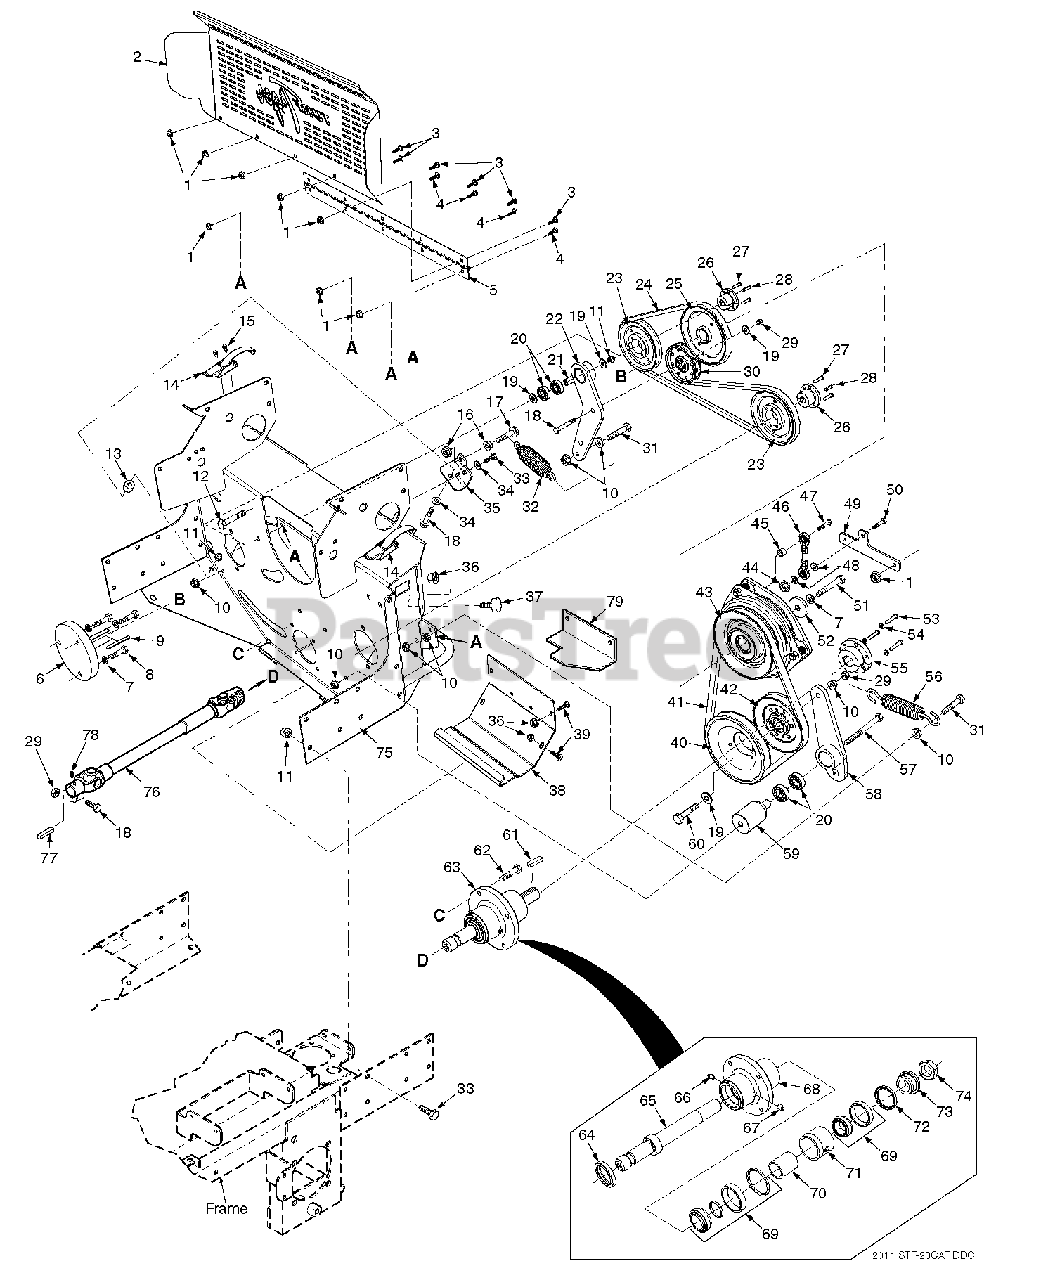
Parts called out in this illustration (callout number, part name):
1	Nut, Serrated Flange 1/4-20
2	Belt Guard, Rear
3	Bolt, Carriage 1/4-20 x 1/2"
4	Bolt, Carriage 1/4-20 x 3/4"
5	Hinge, Belt Guard
6	Stub Shaft
7	Lockwasher, 7/16" Spring
8	Bolt, Hex Head M10 x 1.5 x 35
9	Key, 1/4 x 1/4 x 3-1/4"
10	Nut, Serrated Flange 3/8-16
11	Nut, Elastic Stop 3/8-16
12	Bolt, Hex Head 3/8-16 x 1-3/4" Grd 8
13	Spacer
14	Latch, Hood
15	Screw, #10-32 x .56
16	Nut, Serrated Flange 1/2-13
17	Bolt, Hex Head 1/2-13 x 2" Grd 8
18	Bolt, Hex Head 3/8-16 x 1-3/4"
19	Washer, 3/8" Hardened
20	Ball Bearing
21	Spacer, Idler Bearing
22	Idler Arm Weldment, Pump Drive
23	Pulley, 5.75" O.D.
24	Belt, Pump Drive
25	Pulley, 6.35 Dia. - 1.125 Bore
26	Tapered Hub, 17mm Bore
27	Bolt, Hex Head 1/4-20 x 1" Grd 8
28	Key, 5 x 5 x 35 mm
29	Nut, Center Lock 3/8-16
30	Pulley, Idler 4" Dia.
31	Bolt, Hex Head 3/8-16 x 1-1/2" Grd 8
32	Spring, Transmission Idler
33	Bolt, Hex Head 3/8-16 x 1"
34	Flatwasher, 3/8-.391 x .938 x .105
35	Bracket
36	Nut, Serrated Flange 5/16-18
37	Bumper, Rubber
38	Cover, Rear
39	Bolt, Carriage 5/16-18 x 3/4"
40	Pulley, 6.35 Tapered Bore
41	Belt, Deck Drive
42	Pulley, Idler 5" Dia.
43	Clutch, Ogura GT 3.5 - 1.125 Bore
44	Nut, Hex Elastic Stop 5/16-18
45	Spacer
46	Rod Assembly, Clutch Anti-Rotation
47	Bolt, Hex Head 5/16-18 x 1-1/2"
48	Flatwasher, 5/16"
49	Bracket, Anchor, Anti-Rotation
50	Bolt, Hex Head 5/16-18 x 1-1/4"
51	Bolt, Hex Head 7/16-20 x 2-1/4"
52	Flatwasher, 7/16-.469 x 1.75 x .25
53	Bolt, Hex Head 1/4-20 x 1-3/8"
54	Lockwasher, 1/4" Spring
55	Tapered Hub, 1" Bore
56	Spring, PTO
57	Bolt, Hex Head 3/8-16 x 4-1/2" Grd 8
58	Idler Arm Weldment, PTO Drive
59	Pivot, Idler PTO
60	Bolt, Hex Head 3/8-16 x 2-1/2" Grd 8
61	Key, 1/4 x 1/4 x 1-1/2"
62	Bolt, Hex Head 5/16-18 x 1-3/4" Grd 8
63	Spindle Assembly, Deck Drive
64	Seal, 2.0 OD x 1.5 Bore
65	Shaft, Deck Drive
66	Grease Fitting, 1/4-28
67	Relief Fitting
68	Spindle Housing
69	Roller Bearing Tapered
70	Spacer, Inside
71	Spacer, Outside
72	Seal, 2.0 OD x 1.625 Bore
73	Spindle Bushing, Bottom
74	Nut, 1.06-18 Thread
75	Pump Mounting Plate Weldment
76	Driveshaft
77	Key, 1/4 x 1/4 x 1"
78	Set Screw, 3/8-16 x 3/4" Torx Socket
79	Bracket, Idler Stop
